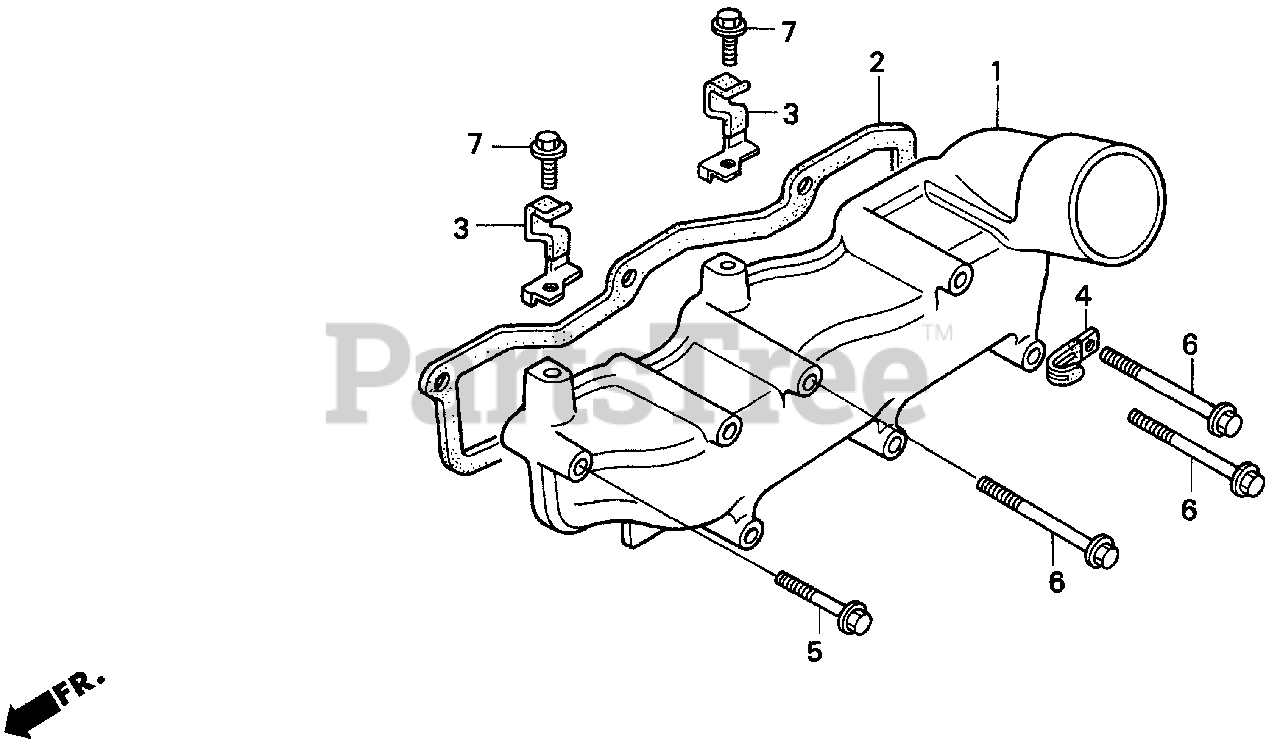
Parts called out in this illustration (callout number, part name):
1	MANIFOLD, IN.
2	GASKET, IN. MANIFOLD (NON-ASBESTOS)
3	CLAMP, WIRE
4	CLIP, CABLE
5	BOLT, FLANGE (6X40)
6	BOLT, FLANGE (6X65)
7	BOLT, FLANGE (6X10)
